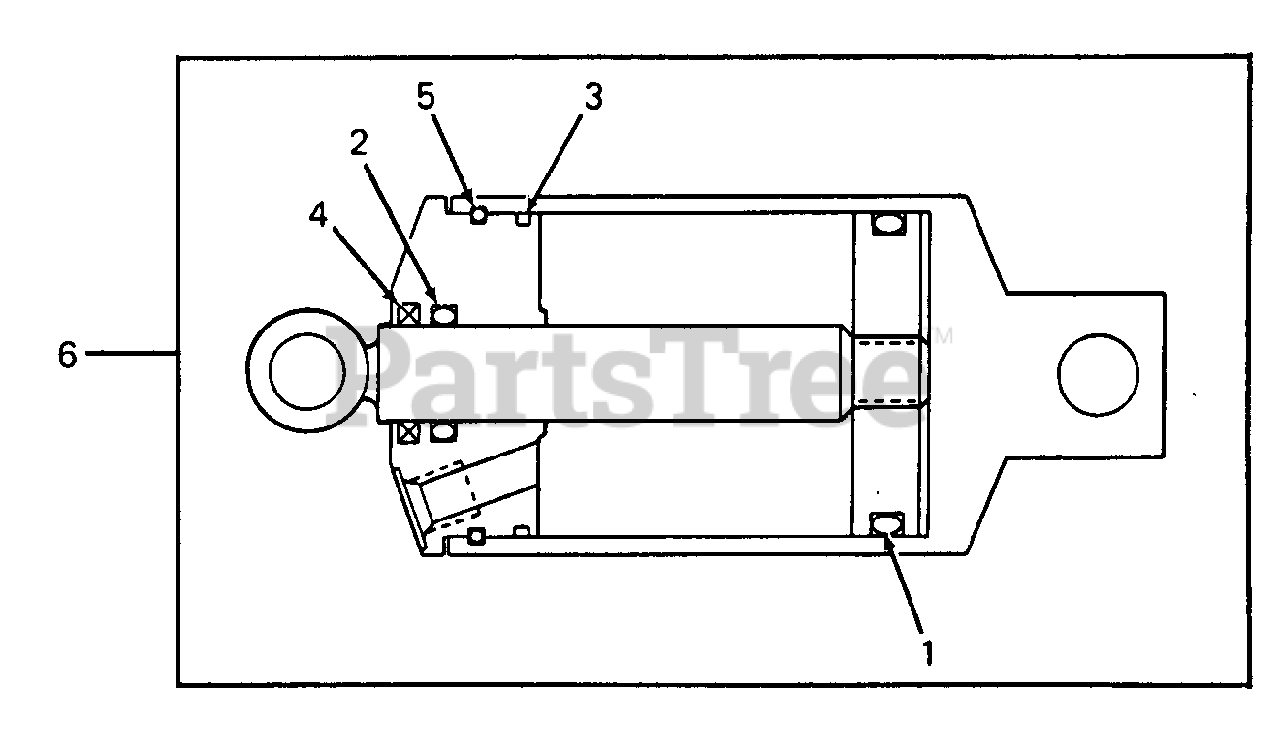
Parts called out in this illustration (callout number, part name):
4	Seal, Hydraulic Cylinder Piston Rod Wiper
5	Retainer, Hydraulic Cylinder Front Head
6	Cylinder, Hydraulic
